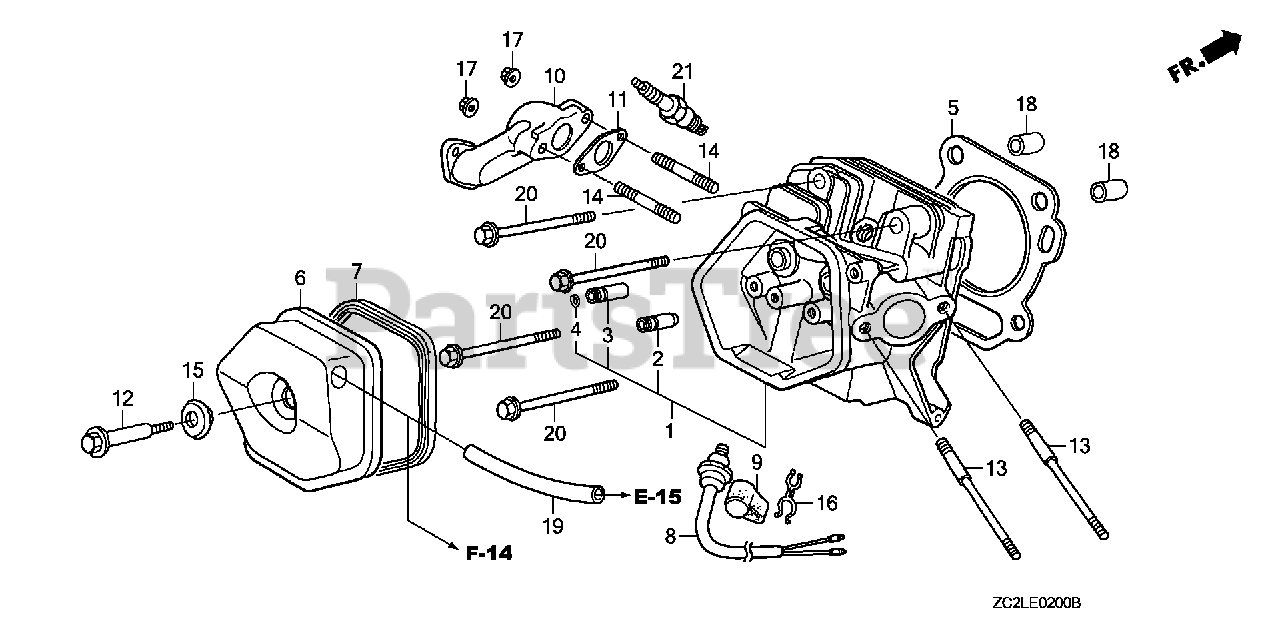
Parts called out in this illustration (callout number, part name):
1	CYLINDER HEAD
2	GUIDE, VALVE (OVER SIZE)
3	GUIDE, EX. VALVE (OVER SIZE)
4	CLIP, VALVE GUIDE
5	GASKET, CYLINDER HEAD
6	COVER, HEAD
7	GASKET, HEAD COVER
8	SWITCH, THERMO
11	GASKET, EX. PIPE
12	BOLT, HEAD COVER
13	BOLT, STUD (8X106)
14	BOLT, STUD (8X32)
15	WASHER, HEAD COVER
16	CLIP, WIRE HARNESS
17	NUT, FLANGE (8MM)
18	PIN, DOWEL (12X20)
20	BOLT, FLANGE (10X80)
21	SPARK PLUG (BPR5ES) (NGK)
21	SPARK PLUG (W16EPR-U) (DENSO)
